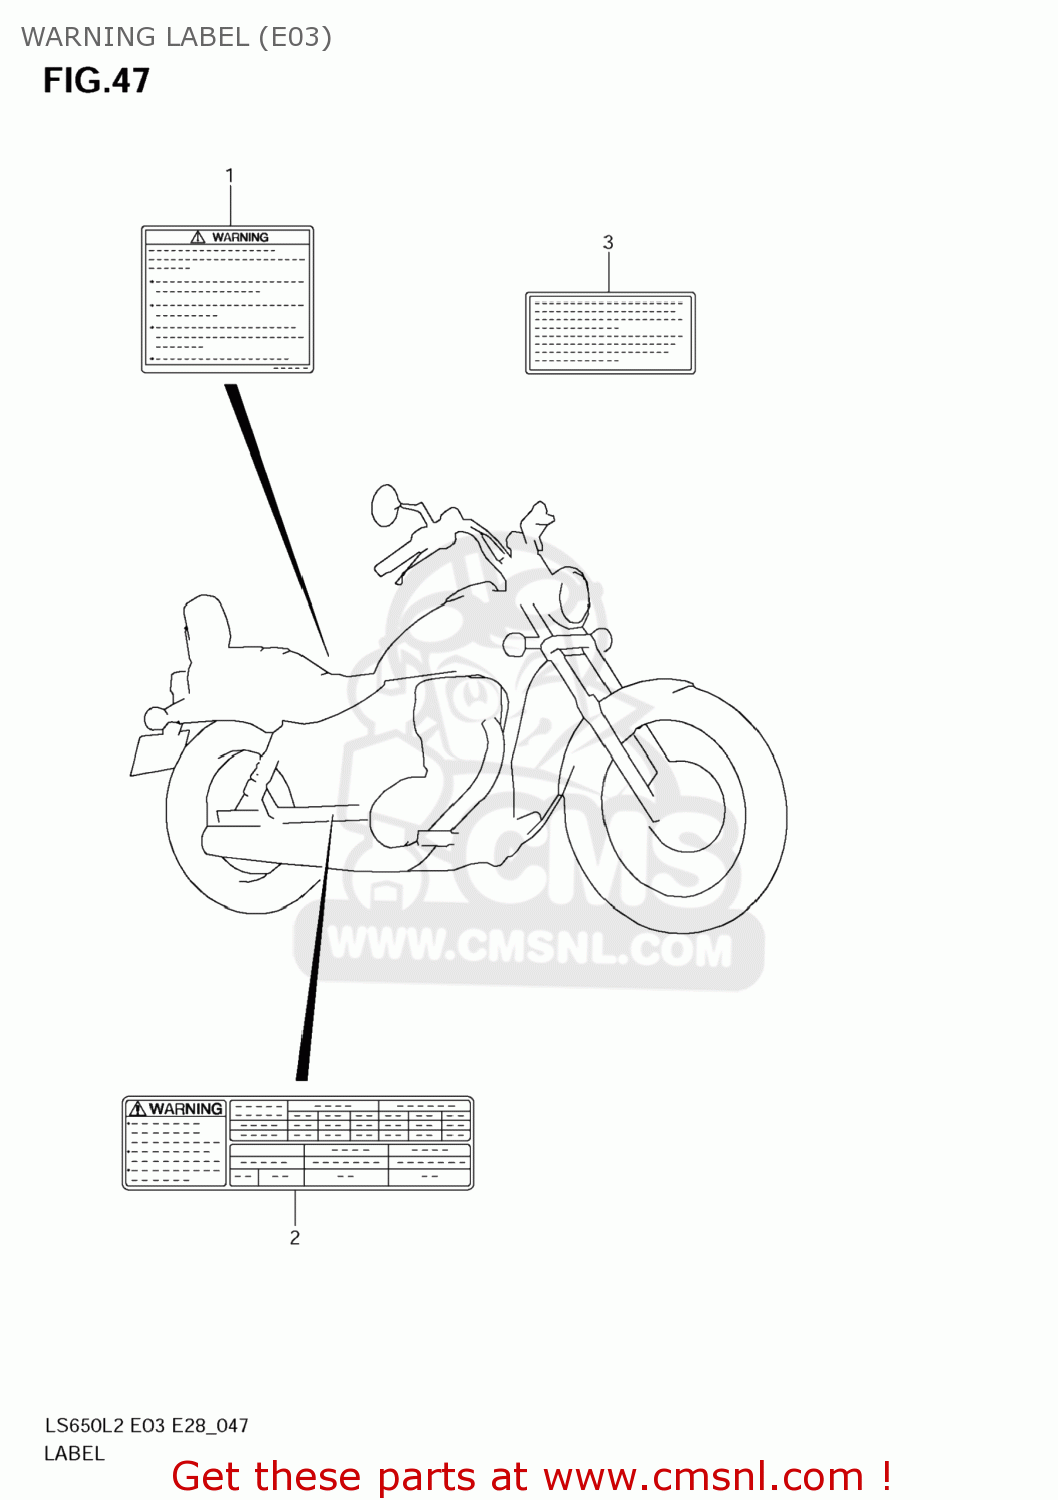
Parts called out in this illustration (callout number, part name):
1	LABEL,GENERAL WARNING
2	LABEL,TIRE INFORMATION
3	LABEL,MANUAL NOTICE
4	MANUAL,OWNER'S
